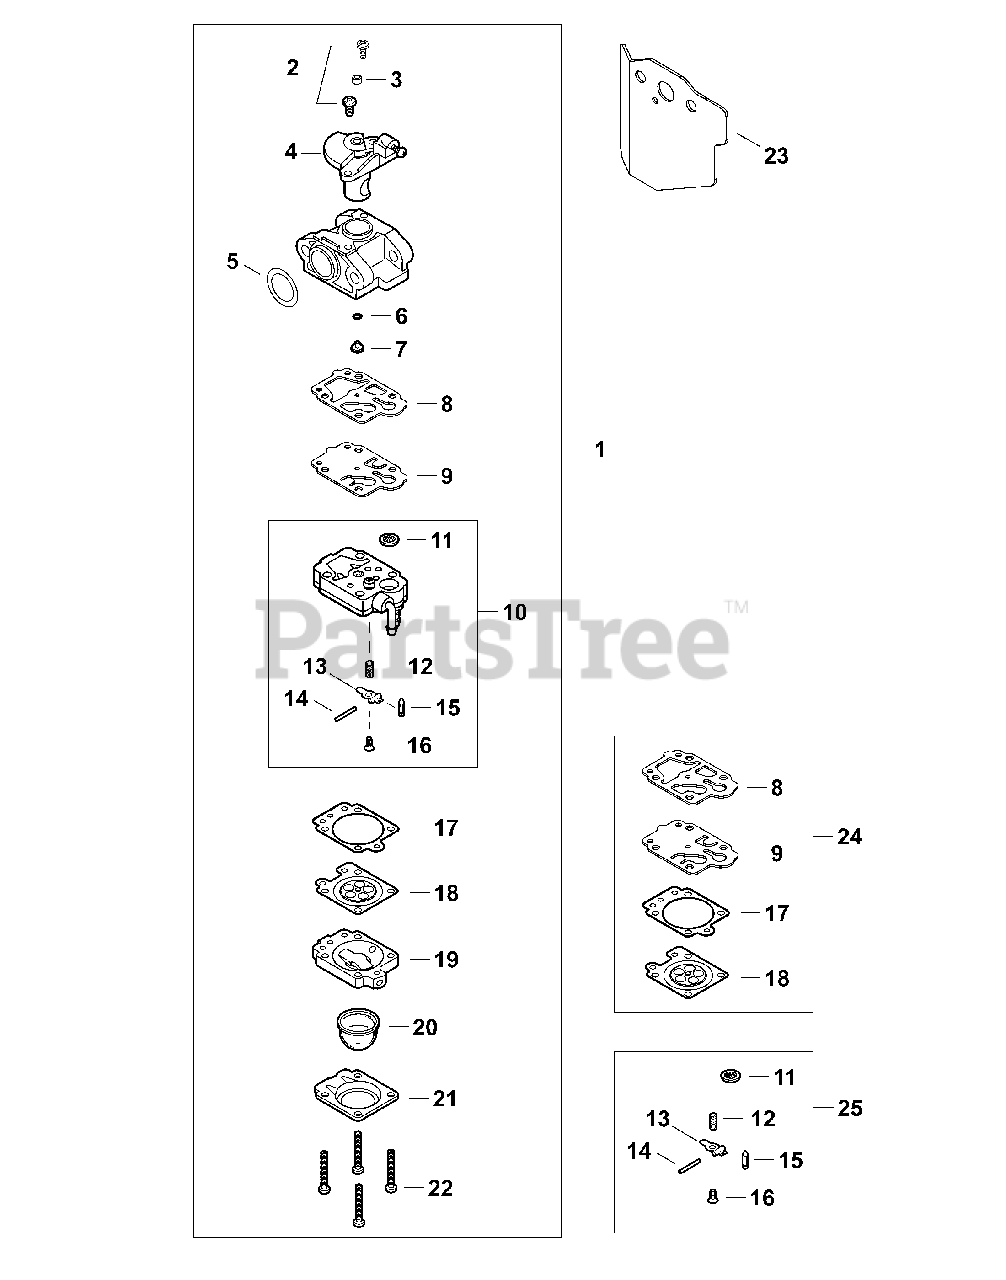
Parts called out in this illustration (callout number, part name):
1	CARBURETOR
2	SCREW, THROTTLE COLLAR
4	VALVE ASSY, THROTTLE
5	O-RING 15
7	JET, MAIN #34
8	GASKET, PUMP
9	DIAPHRAGM, FUEL PUMP
10	BODY ASSY, PUMP
11	SCREEN, FUEL INLET
12	SPRING, METERING LEVER
13	LEVER, METERING
14	PIN, METERING LEVER
15	VALVE, INLET NEEDLE
17	GASKET, METERING DIAPHRAGM
18	DIAPHRAGM, METERING
19	BODY ASSY, PURGE
20	BULB, PURGE
21	RETAINER, PURGE BULB
23	GASKET, CARBURETOR
24	GASKET / DIAPHRAGM KIT
25	VALVE KIT, INLET NEEDLE
